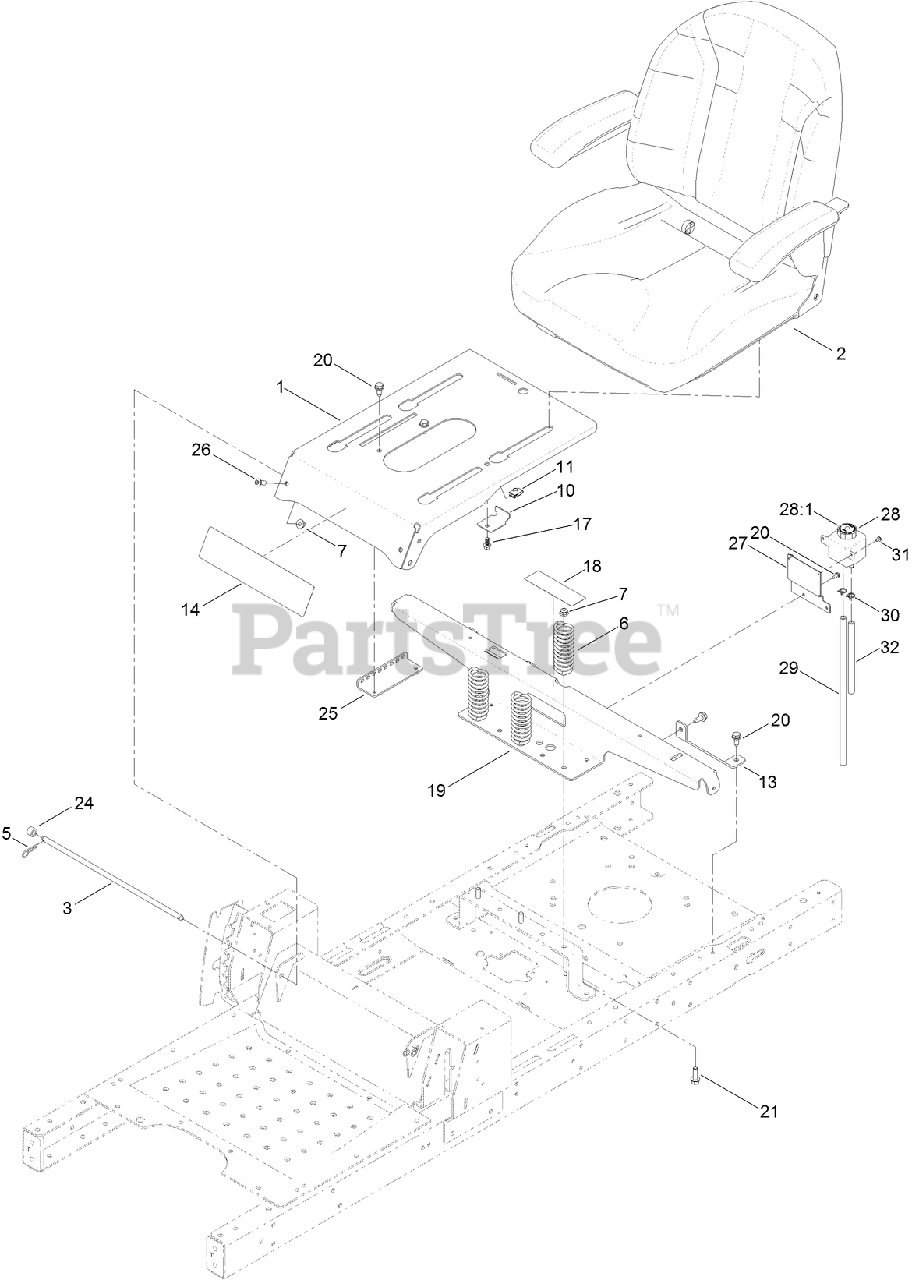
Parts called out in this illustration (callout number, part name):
2	SEAT ASM
3	ROD-STOP
5	PIN-COTTER
6	SPRING-COMPRESSION
7	NUT-HF, NI
10	BRACKET-STOP, SEAT
13	SUPPORT-TANK, REAR
14	DECAL-TIMECUTTER
17	SCREW-HHF
18	DECAL-SERVICE, CE
19	SUPPORT-POD, WIDE
20	SCREW-HWHTF
21	SCREW-HHF
24	BUSHING-LEVER, LIFT
25	BRACKET-LATCH, SEAT
26	SCREW-HSBH
27	MOUNT-TANK
28	TANK-HYD
28:1	CAP-RESERVOIR, HYD
29	HOSE-OVERFLOW
30	CLAMP-HOSE
31	SCREW-HHFTF
32	HOSE-OVERFLOW
